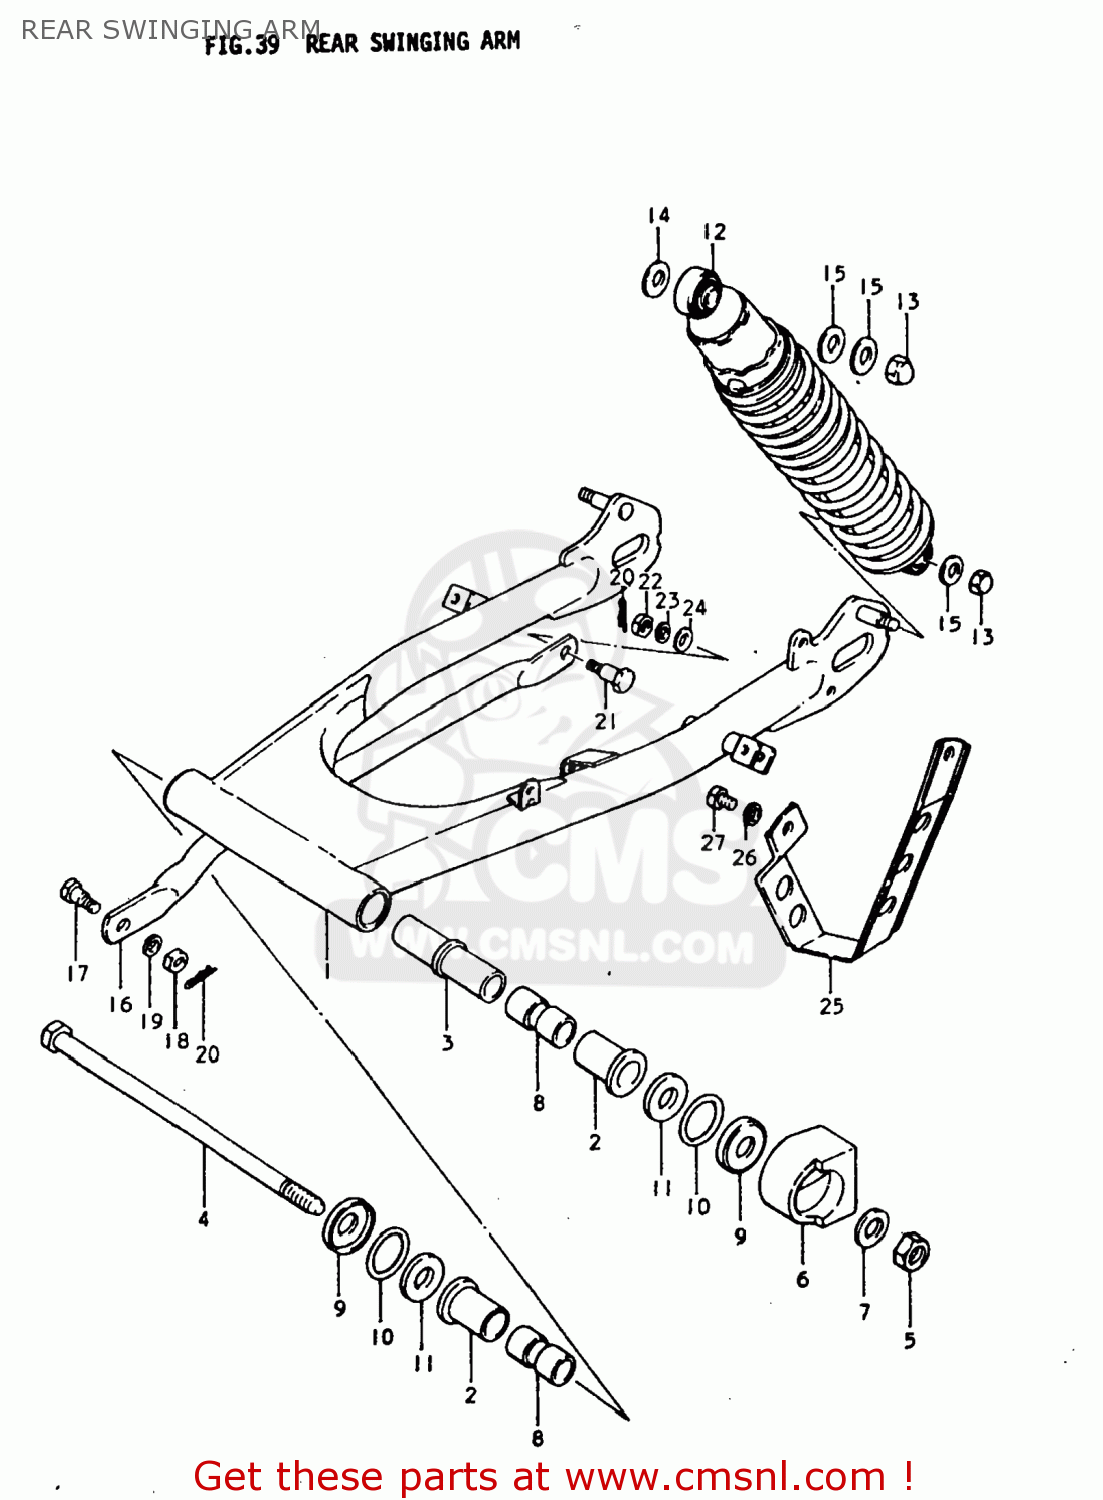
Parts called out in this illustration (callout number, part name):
1	SWING ARM ASSEMBLY,REAR
2	BUSH
3	SPACER,SWING ARM,CENTER
4	SHAFT,REAR SWING ARM
5	NUT 14MM
6	BUFFER,CHAIN TOUCH DEFLECTOR
7	WASHER
8	SPACER
9	COVER
10	O RING(D:3,ID:29.5)
11	WASHER(14.5X29X2.3)
12	ABSORBER ASSEMBLY,REAR SHOCK
13	NUT, LOWER LH
14	WASHER
15	WASHER
16	TORQUE LINK,REAR
17	BOLT(8X22.5)
18	NUT
19	LOCK WASHER
20	CLIP
21	BOLT(10X32.5)
22	NUT
23	LOCK WASHER
24	WASHER
25	GUIDE,CHAIN
26	LOCK WASHER
27	BOLT 8X12
